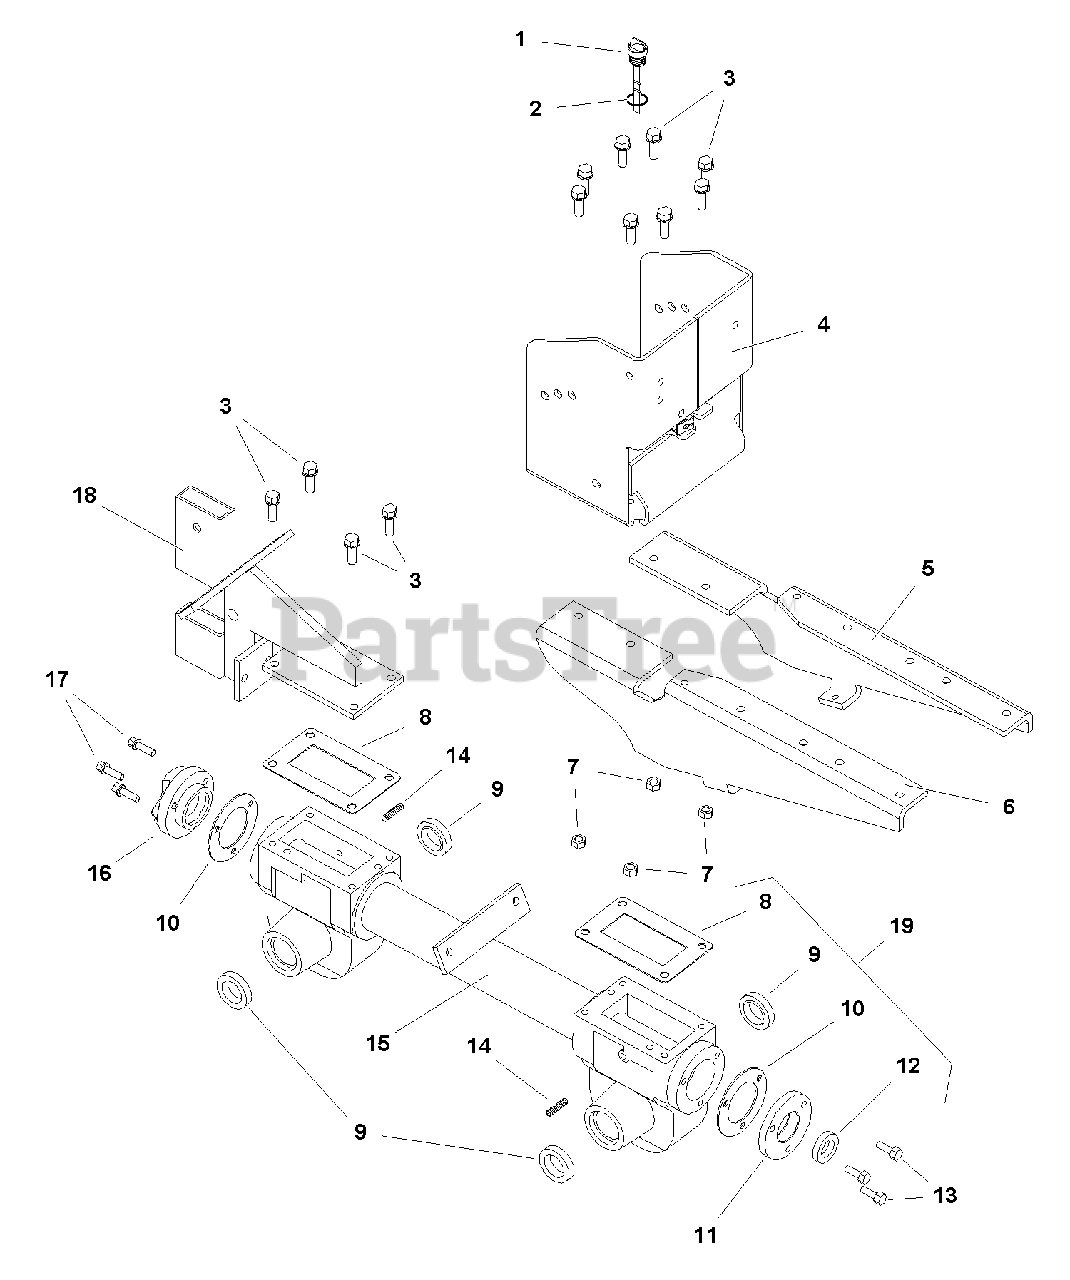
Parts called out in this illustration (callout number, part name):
2	O, RING, Dipstick
3	BOLT, Hex Flange Head 5/16" - 18 x 3/4"
4	COVER PLATE & MOUNT
5	BRACKET, Engine Mount LH
6	BRACKET, Engine Mount RH
7	NUT, Hex Flange 5/16" - 18 Two, Way Lock GA
8	GASKET, Housing & Transmission Cover
9	SEAL, Housing
10	GASKET, Bearing Cap Front/Rear
11	CAP, Rear Bearing
12	SEAL, Oil, Drive Shaft
13	BOLT, Hex Flange Head 1/4" - 20 x 3/4"
14	PLUG, Pipe Socket Head, 1/4" - 18 Oil Check
15	TRANSMISSION, Housing, Tiller Casting
15	TRANSMISSION ASSEMBLY, Complete
16	CAP, Rear Bearing
17	BOLT, Hex Flange Head 1/4" - 20 x 7/8"
18	BRACKET, Depth Regulator RT
19	GASKET KIT, Oil Seal ( Includes Ref. 8, 9, 10, and 12)
